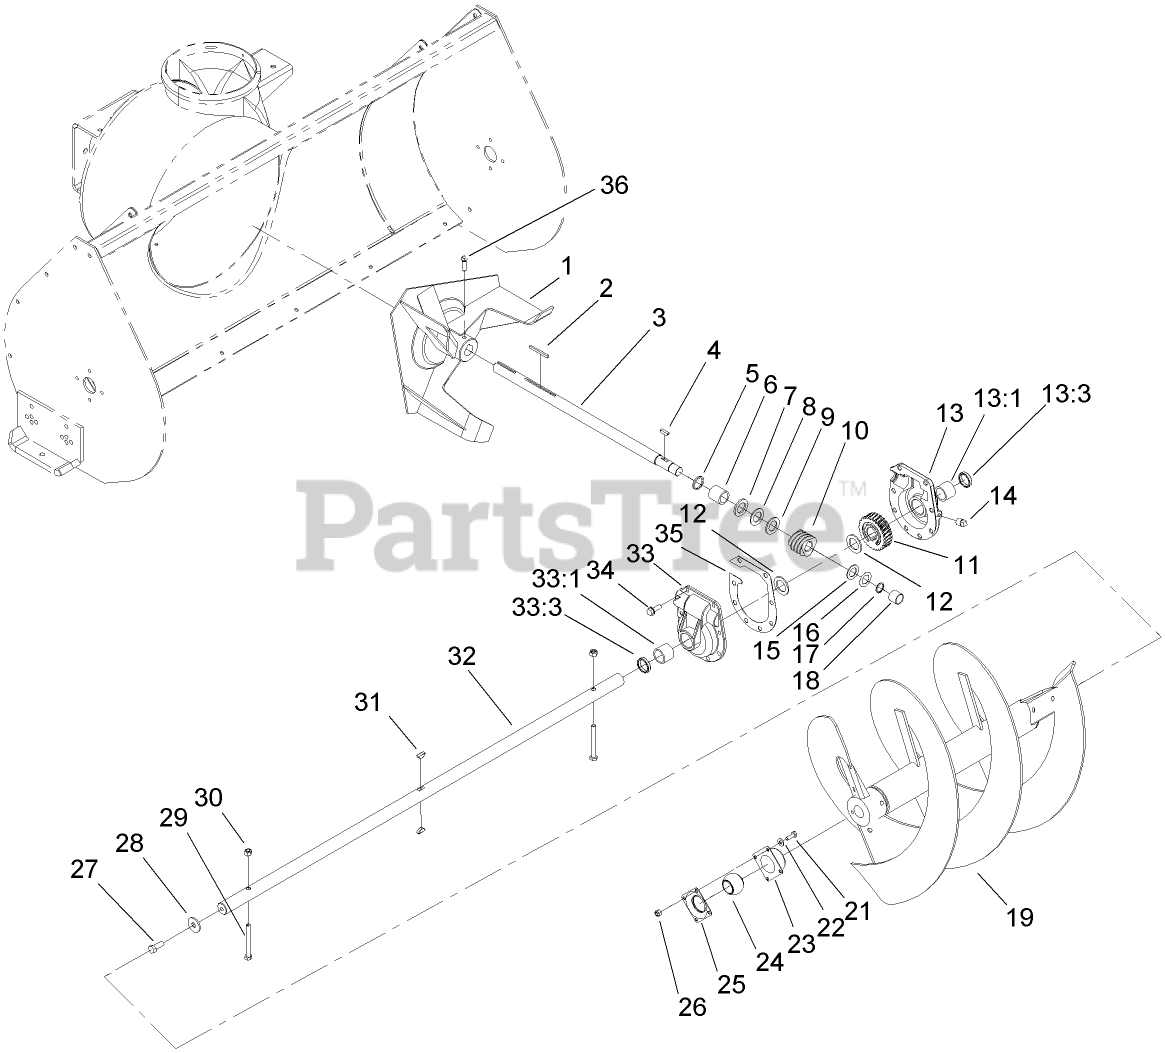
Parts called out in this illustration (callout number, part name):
1	IMPELLER ASM
3	SHAFT-IMPELLER
4	KEY-WOODRUFF
5	RING-QUAD
6	BUSHING-SPECIAL
7	WASHER-THRUST
8	BEARING-THRUST
9	THRUST-WASHER
11	GEAR-WORM, 27T
12	WASHER-THRUST
13	LH GEAR CASE ASM
13:1	BUSHING
13:3	SEAL-OIL
14	PLUG-PIPE, SQH
15	WASHER-THRUST
16	WASHER-SHIM
17	Ring-Snap
18	BUSHING
19	RH AUGER ASM
21	SCREW-HH
22	WASHER-FLAT
23	BEARING-FLANGE, FRONT
24	BEARING
25	BEARING-FLANGE, REAR
26	NUT-LOCK, NI
27	SCREW-HH, LOCK
28	WASHER
29	SCREW-HH
30	NUT-LOCK, NI
31	KEY-WOODRUFF
32	SHAFT-AUGER
33	RH GEAR CASE ASM
33:1	BUSHING
33:3	SEAL-OIL
34	SCREW-TAPTITE
35	GASKET-GEAR BOX
36	SCREW-SET, SQH
